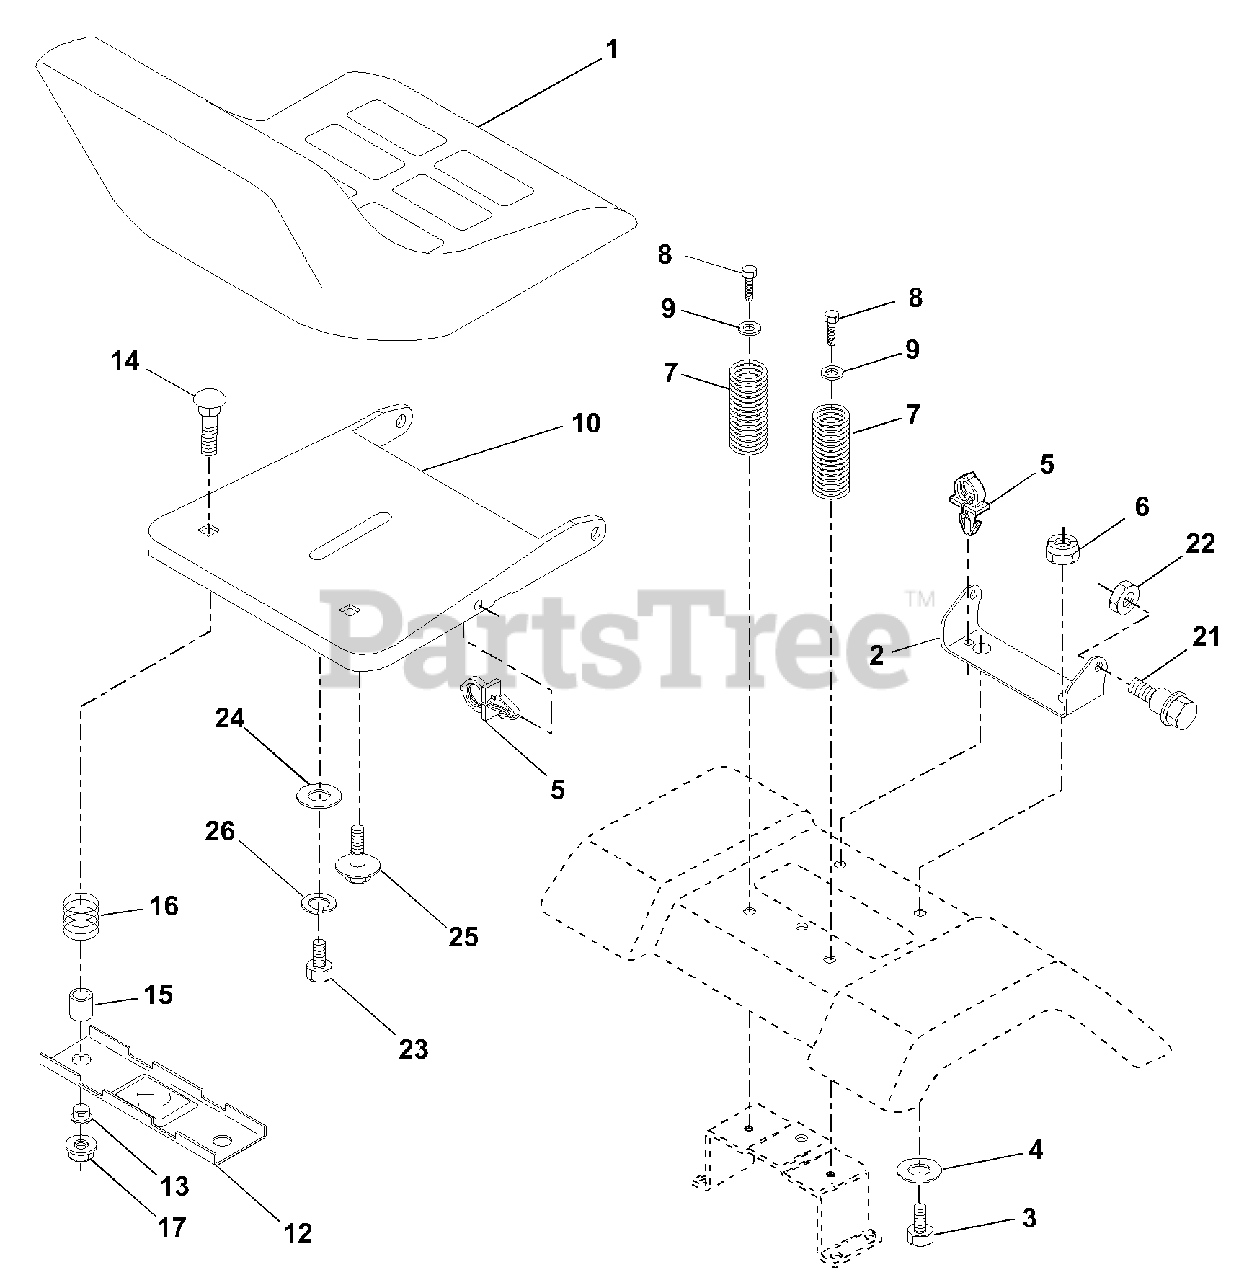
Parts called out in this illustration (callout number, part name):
2	Bracket Seat Pivot
3	Bolt Hex 3/8 - 16 X 1
4	Washer 13/32 X 1 X 10Ga.
5	Clip Push-In Hinged
6	Nut Lock Hex w/Ins 3/8 - 16
7	Spring Seat Cprsn 2 250 Blk Zi
8	Screw 3/8-16 x 1.5
9	Washer 13/32 X 1 X 14 Ga
10	Pan Pnt Seat (Blk)
12	Bracket Pnt Mounting Switch
13	Bushing Snap Blk Nyl
14	Bolt Rdhd Sht Nk 1/4 - 20 X 1 -1/2
15	Spacer Split .28 X .96
16	Spring Cprsn
17	Nut Lock 1/4 Lge Flg
21	Bolt Shoulder 5/16-18 Unc-2A
22	Nut Lock Hex w/Ins 5/16 - 18
23	Bolt Fin Hex 1/2-13 X 7/8 Gr. 5
24	Washer 17/32 X 1-3/16 X 12 Ga
25	Bolt Shoulder 5/16-18 X .62
26	Washer Lock Hvy Hlcl Spr 1/2
